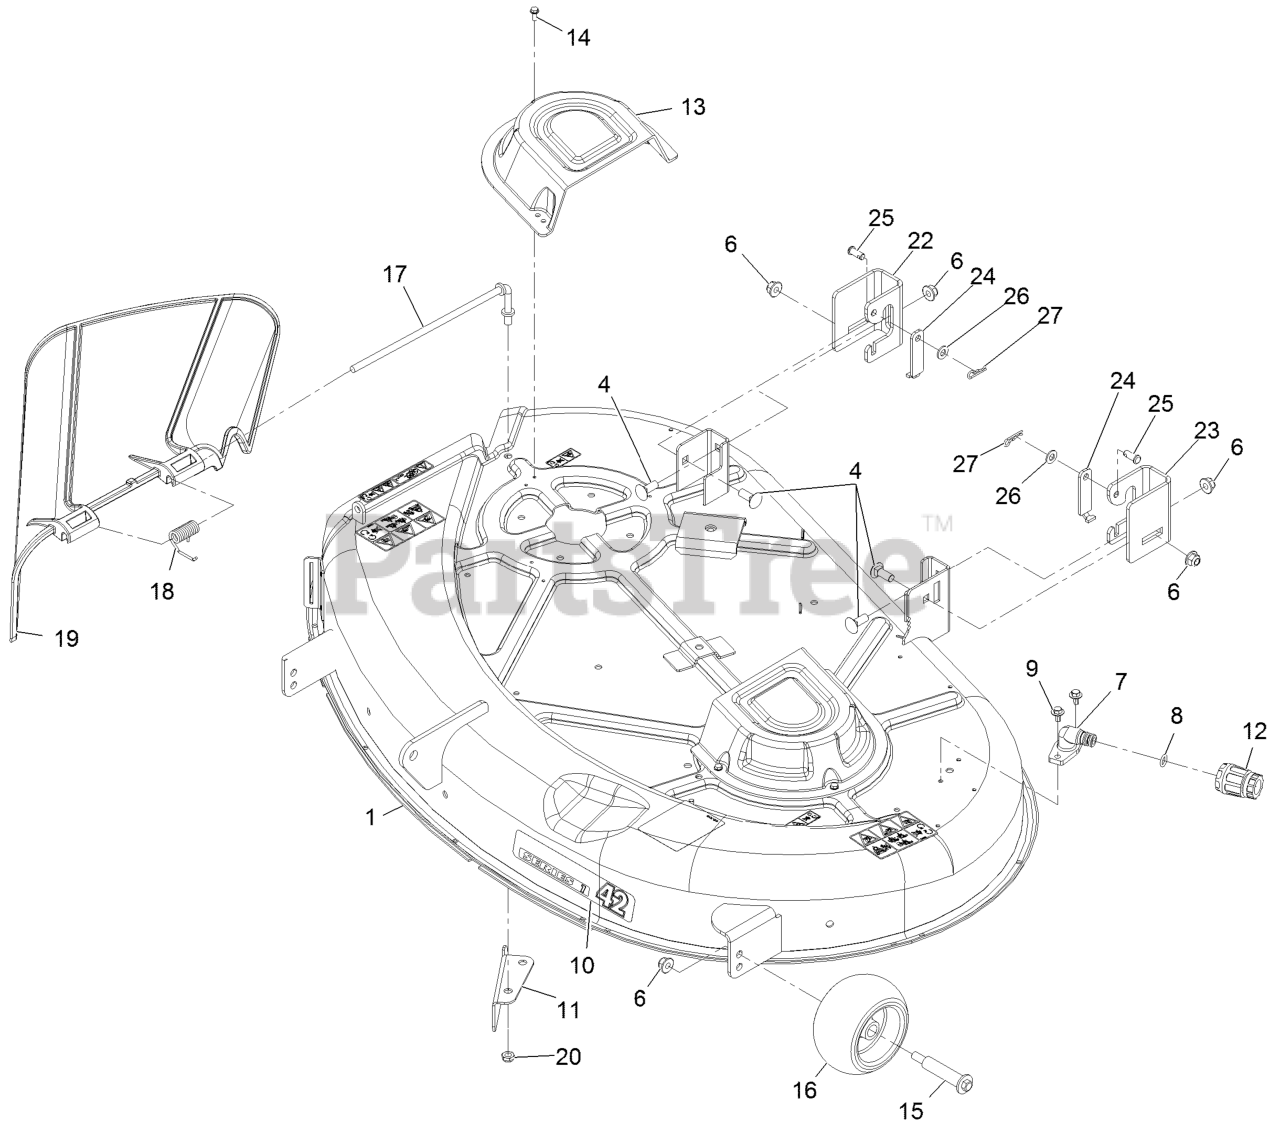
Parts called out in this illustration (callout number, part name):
1	42 INCH DECK AND DECAL AS
4	BOLT-CARR
6	NUT-HF, NI
9	SCREW-HHFTF
10	DECAL-SERIES 1 - 42
11	BAFFLE-CUTOFF
12	CONNECTOR-HOSE
13	COVER-BELT
14	SCREW-TAPTITE
15	BOLT-SHOULDER
16	ROLLER-SCALP, ANTI
17	ROD-PIVOT
18	SPRING-TORSION
19	DEFLECTOR
22	BRACKET - HANGER, RR
23	BRACKET - HANGER, LR
24	LINK - DECK RETENTION
25	PIN-CLEVIS
26	WASHER-PLAIN
27	PIN-COTTER
